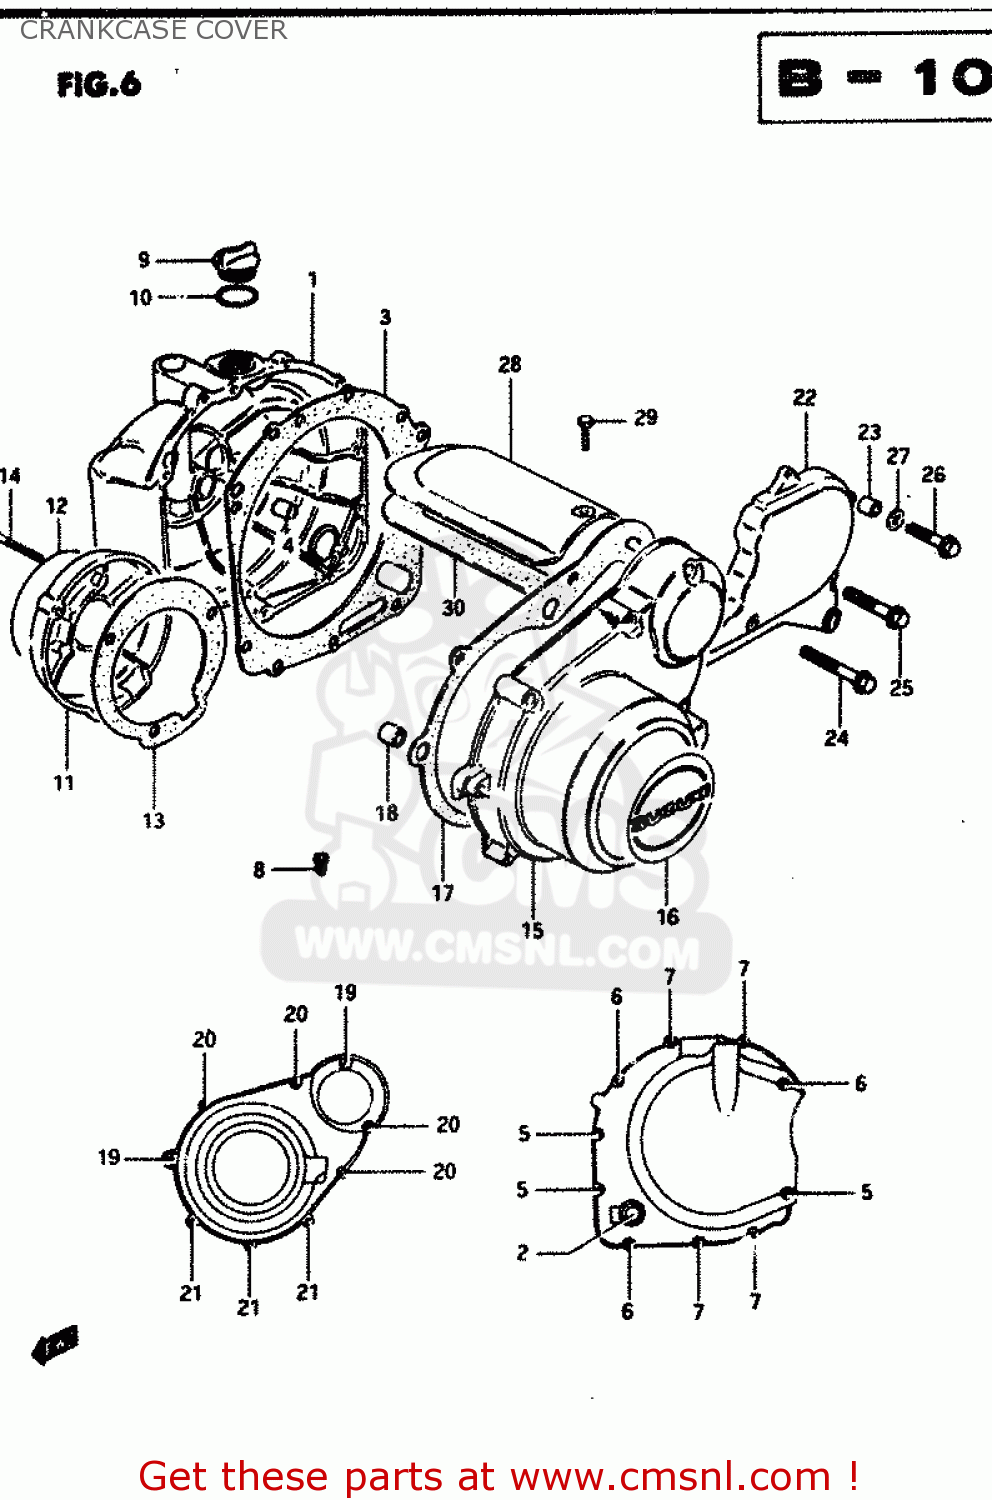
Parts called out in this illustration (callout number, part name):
1	COVER,CLUTCH
2	LENS,OIL LEVEL CHECK
3	GASKET,MAGNETO COVER (N (MCA)
4	PIN
5	BOLT (6X35)
6	BOLT (6X30)
7	BOLT
8	JET
9	CAP
10	O RING(D:2.2,ID:32)
11	COVER,CONTACT BREAKER
12	EMBLEM,CONTACT BREAKER COVER
13	GASKET,CONTACT BREAKER COVER (NAS)
14	BOLT (5X30)
15	COVER,MAGNETO
16	EMBLEM,MAGNETO COVER
17	GASKET,MAGNETO COVER (MCA)
18	PIN
19	BOLT
20	BOLT (6X40)
21	BOLT (6X35)
22	COVER,SPROCKET
23	PIN
24	BOLT (6X30)
25	BOLT (6X20)
26	BOLT
27	WASHER
28	COVER,STARTER MOTOR
29	BOLT
30	GASKET,STARTER MOTOR COVER (MCA)
